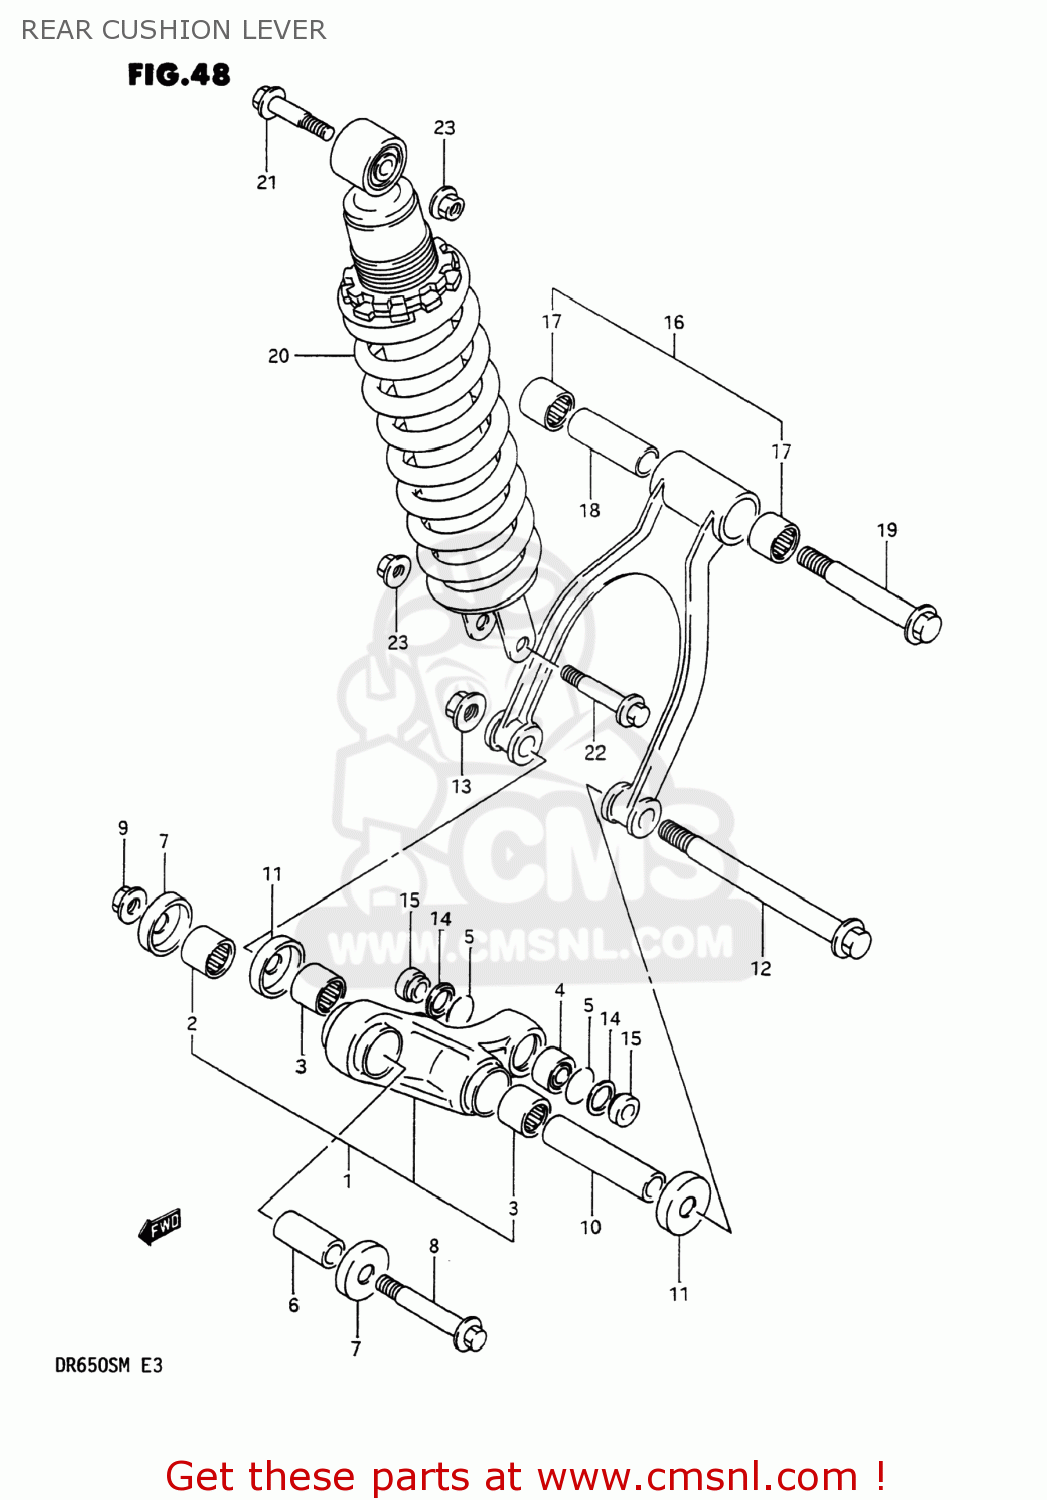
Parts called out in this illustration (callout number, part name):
1	LEVER SET,REAR CUSHION
2	BEARING(20X27X30)
3	BEARING(20X27X23.5)
4	BEARING,REAR SHOCK ABSORBER
5	RING
6	SPACER,RR CUSHION LEVER FR
7	SEAL,RR CUSHION LEVER FR DUST
8	BOLT,RR CUSHION LEVER FR
9	NUT 12MM
10	SPACER (14X20X78)
11	SEAL,RR CUSHION LEVER CTR DUST
12	BOLT,RR CUSHION ROD LWR
13	NUT
14	SEAL,DUST RR SHOCK ABSORBER
15	COLLAR
16	LEVER SET,REAR CUSHION
17	BEARING(20X27X23.5)
18	SPACER (14X20X63)
19	BOLT,RR CUSHION ROD UPR
20	ABSORBER ASSEMBLY,REAR SHOCK
21	BOLT(10X50)
22	BOLT(10X52)
23	NUT
